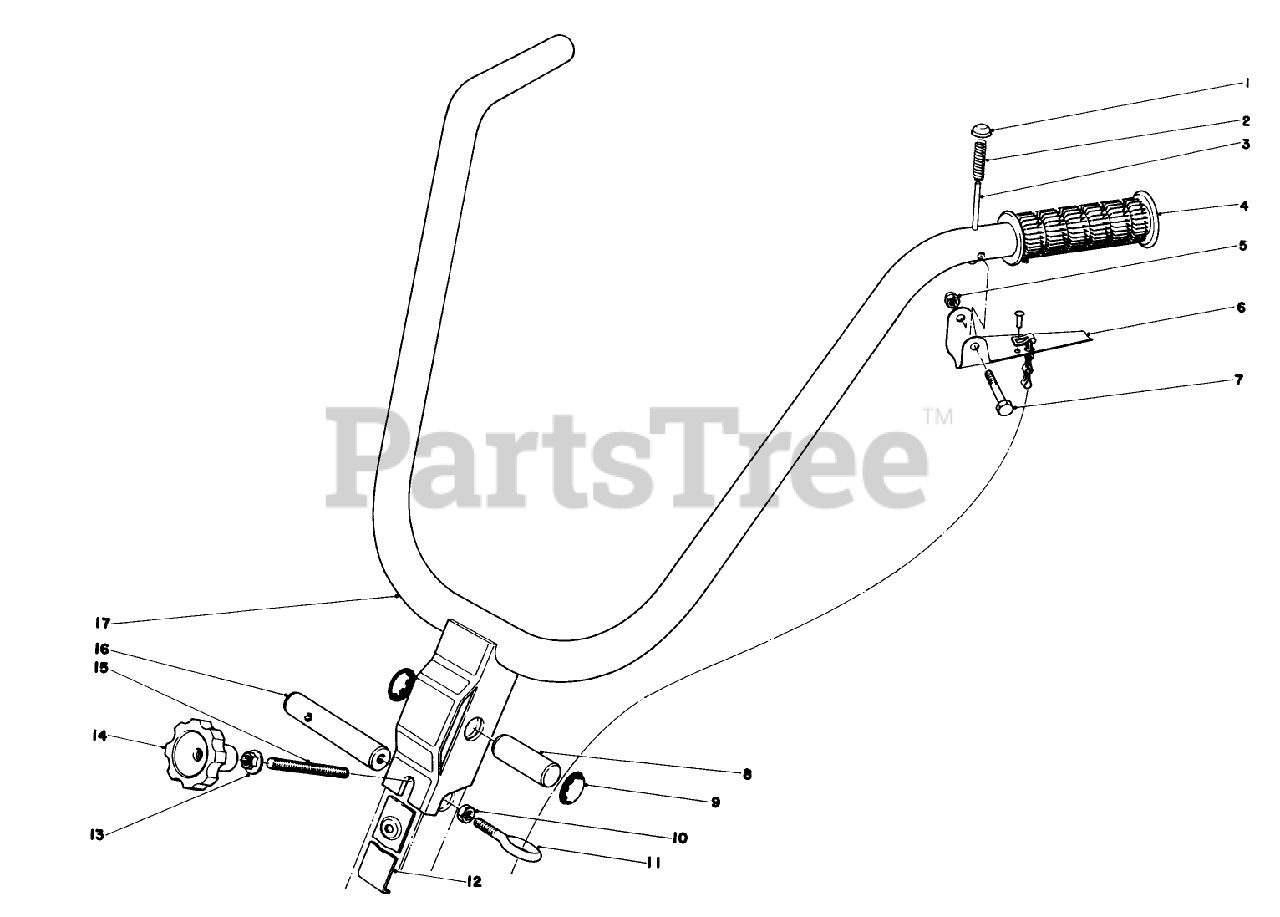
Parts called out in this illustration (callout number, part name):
2	Spring
4	GRIP-HANDLE
5	NUT-CAP
7	SCREW-HH
10	NUT-JAM
12	Stop Wheel Yoke (Model 58336)
13	NUT-FLANGE
